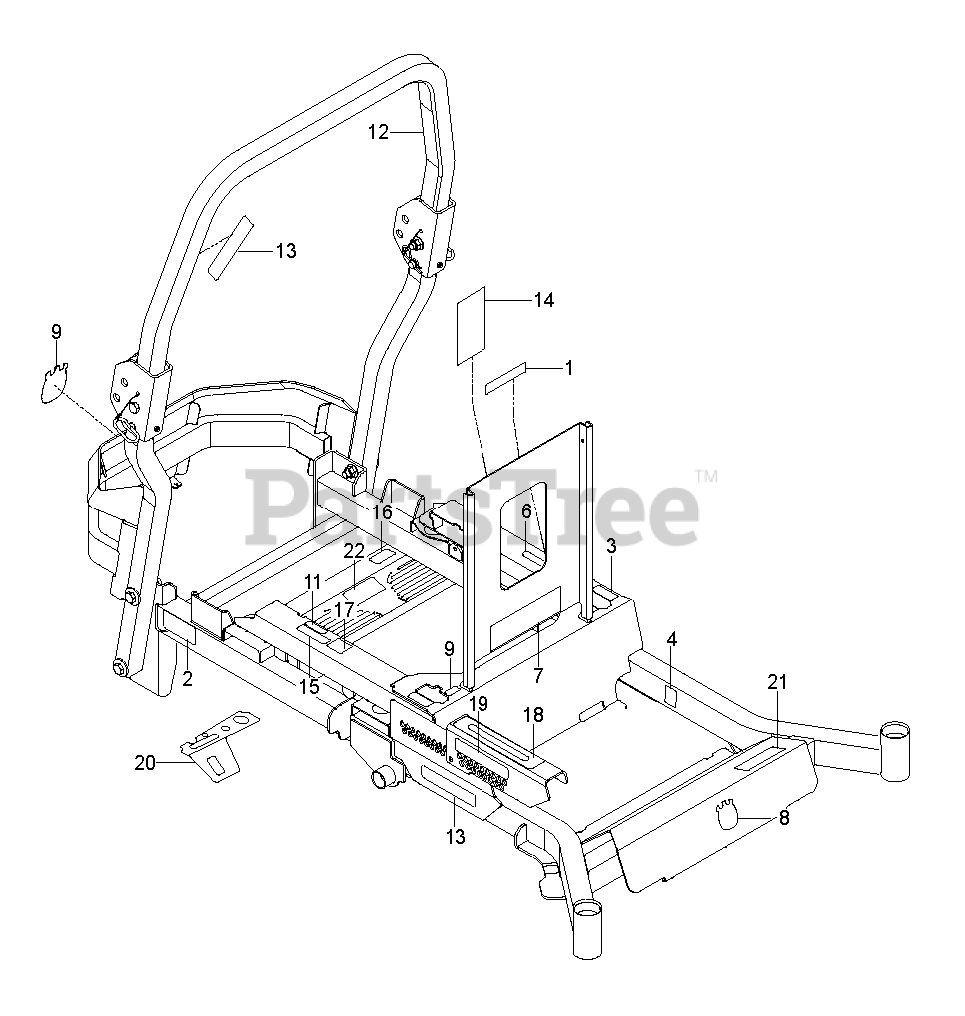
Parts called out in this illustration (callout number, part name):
1	EURO DECAL-BATTERY WARNIN6
2	DECAL, BELT DRIVE
3	DECAL.ZTR.MOTCONTRL.SYMBOL.HUS
4	DECAL.80.DBA.AUSTRALIA
5	DECAL.STR.S.T.SYSMBOLONLY.2014
6	DECAL.ZTR.PARKBRAK.SYMBOL.2014
7	DECAL.ZTR.WARNING.SMARTIGNITIN
8	DECAL.AUGER.HUSQ.CROWN.SNOW
9	DECAL, CROWN H, 110MM
10	RP.DECAL.BADGE.170MM.TEXTLOGO
11	DECAL, FUSE
12	DECAL, ROPS
13	DECAL, ROPS, WARNING
14	DECAL, SERVICE
15	DECAL, WARNING SPARK ARRESTOR
16	DECAL, FUEL
17	DECAL, ECM, AUSTRALIA
18	DECAL, HEIGHT
19	DECAL, HEIGHT
20	DECAL, CONTROL, GAS
21	DECAL.PZ29
22	DECAL, OIL TANK
